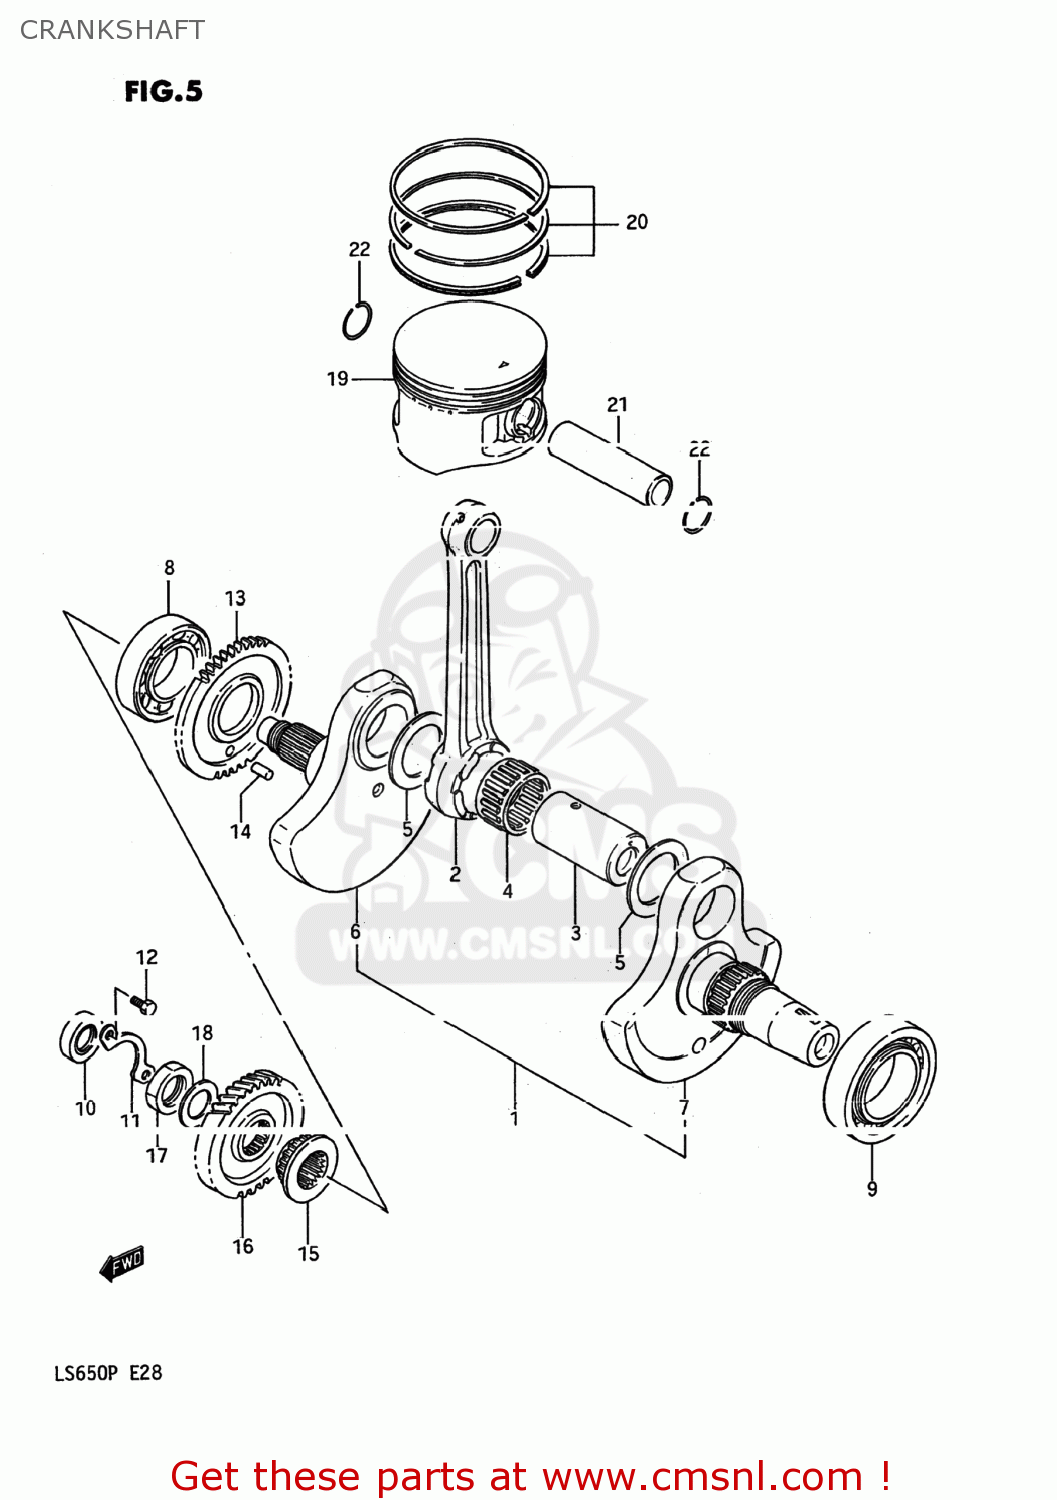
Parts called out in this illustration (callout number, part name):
1	CRANKSHAFT ASSY
2	ROD,CONNECTING
3	PIN,CRANK
4	BEARING
5	WASHER(37X55X1)
6	CRANKSHAFT
7	CRANKSHAFT,L
8	BEARING(35X72X17)
9	BEARING(40X80X18)
10	SEAL,OIL(16X30X6)
11	RETAINER,CRANKSHAFT OIL SEAL,R
12	BOLT 5X16
13	GEAR,CRANK BALANCER DRIVE
14	PIN
15	SPROCKET,CAM CHAIN DRIVE
16	GEAR,PRIMARY DRIVE
17	NUT (20MM)
18	WASHER
19	PISTON
20	RING SET,PISTON
21	PIN,PISTON
22	CIRCLIP
